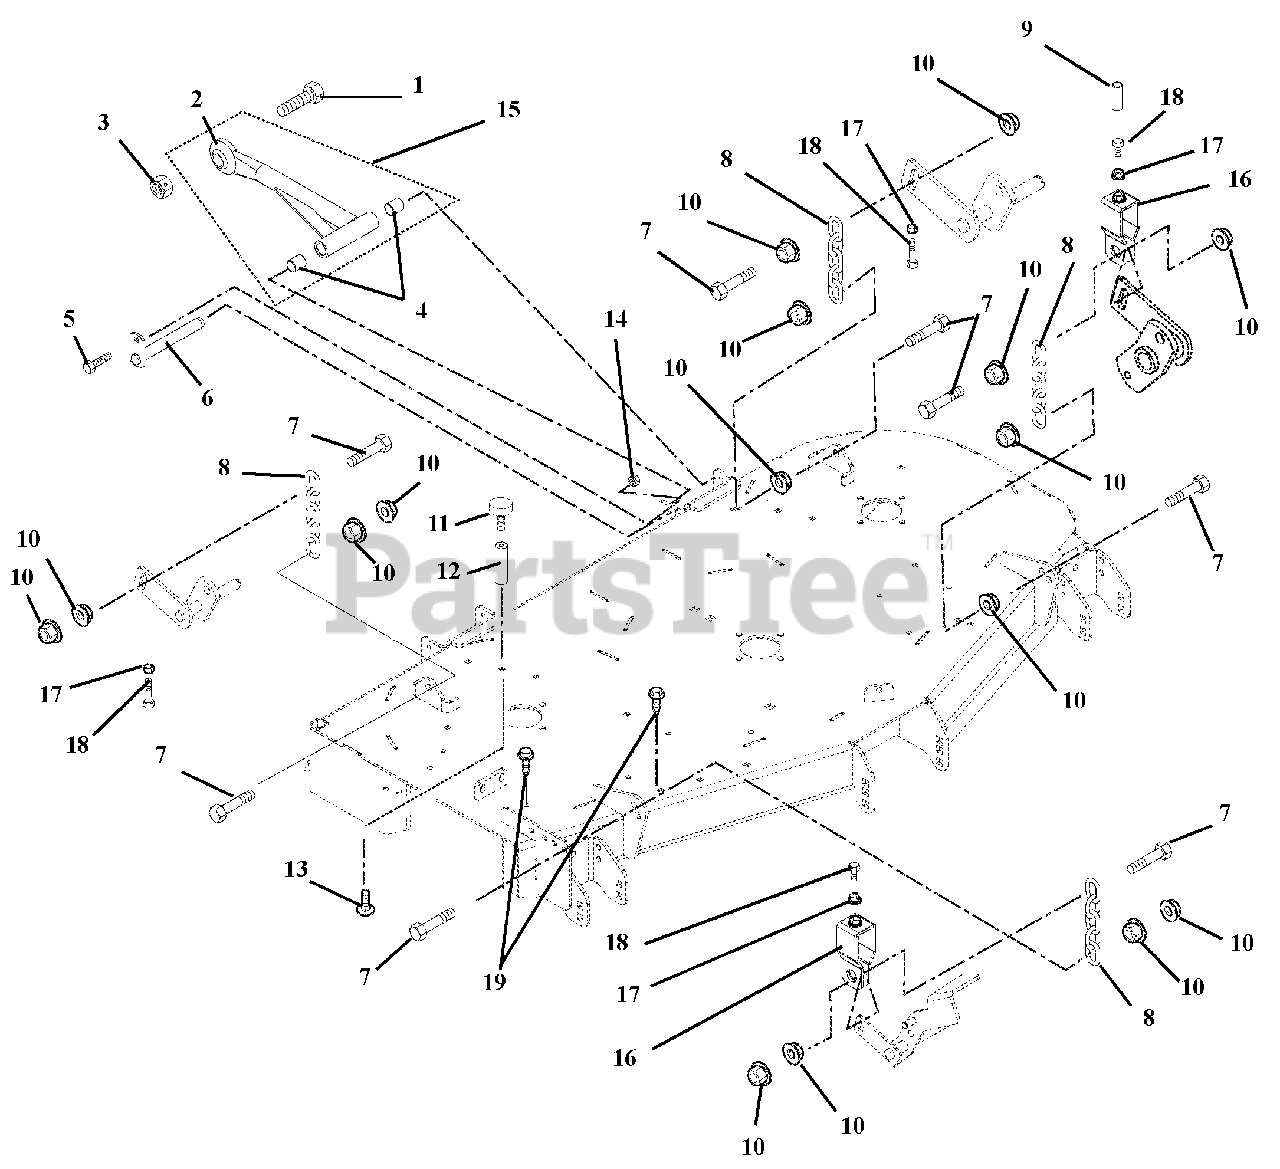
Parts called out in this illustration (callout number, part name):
1	Bolt, Hex .875-9 x 2.75 Grade 5
2	Mower Mounting Arm Weldment
3	Nut, Locking-Center .875-9
4	Bearing, .75 x .875 x 1.00
5	Bolt, Hex .38-16 x .75 Grade 5
6	Weldment, Mower Mounting Pin
7	Bolt, Hex M12-1.75 x 50 Grade 5
8	Chain, Link
9	Cap, Vinyl .50ID x 1.50LG x .055
10	Nut, Spin Lock-Flange M12-1.75
11	Bumper, Rubber
12	Nut, Coupling .31-18 x 3.00
13	Bolt, Round Head Square Neck .31-18 x .75 Loctite with Epoxy Patch
14	Nut, .38-16 Nyloc Flange
15	Assembly, Mower Mounting Arm (Includes item # 2 and item # 4)
16	Bracket, Deck Leveling
17	Nut-Jam .312-18
18	Bolt, Hex .31-18 x 2.00 Full Thread
19	Screw, Tapping .38-16 x .50 Hex Washer Head Thread (992121,136, 137)
